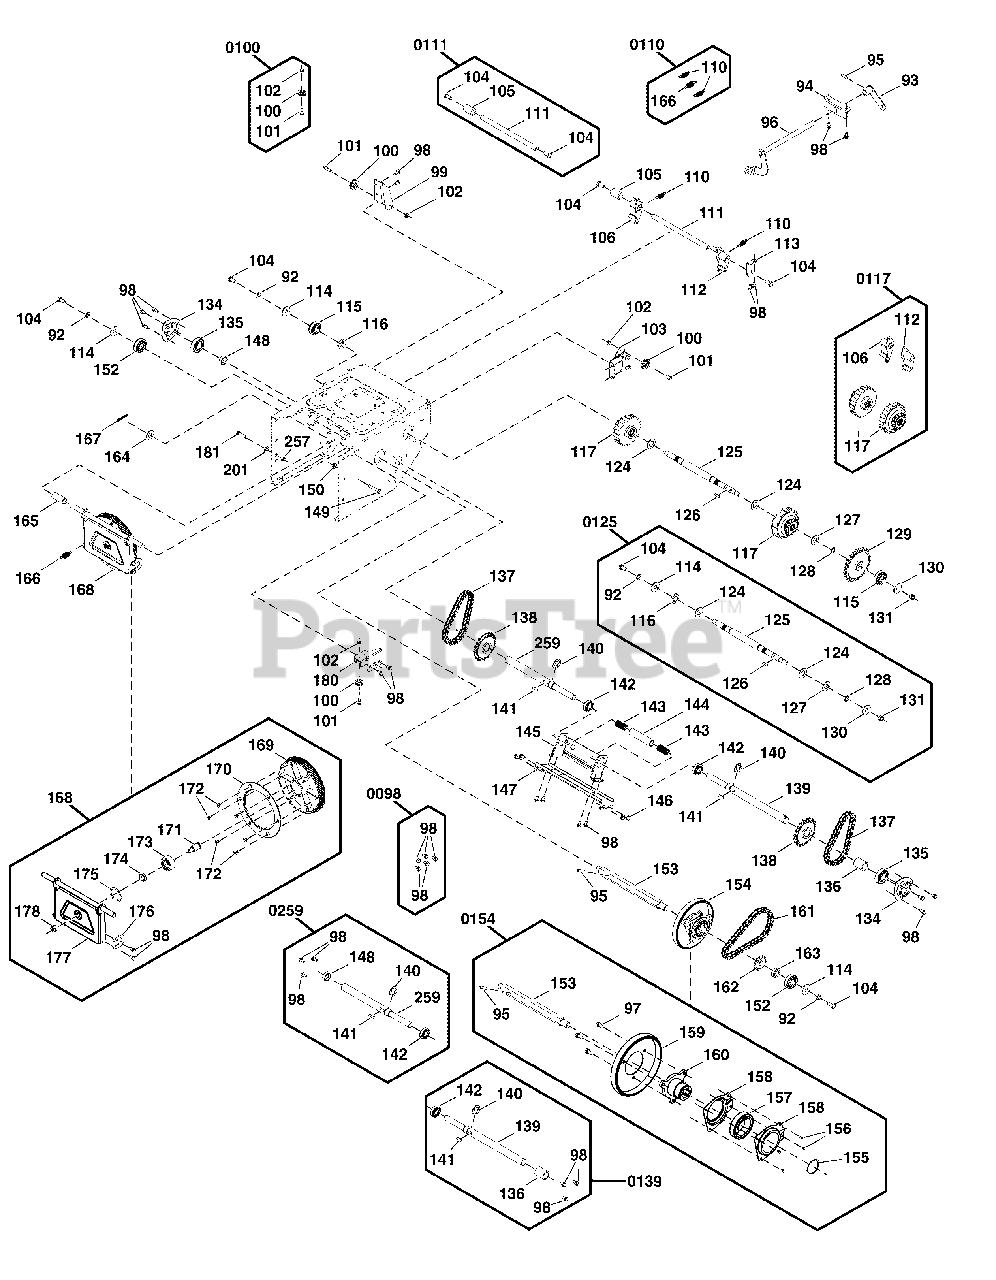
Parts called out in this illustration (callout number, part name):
93	ARM, Speed Select
94	BRACKET, Speed Select
95	PIN, Spring, 6 X 30
96	ROD, Speed Select, Fork
0098	KIT, Hardware
99	BRACKET, Cable Guide, Traction Control
0100	KIT, Pulley, Cable
100	PULLEY, Cable
101	SCREW, M6 X 12, Hex Head Shoulder
103	BRACKET, Cable Guide, Auger Control
105	SLEEVE, PAWL
106	PAWL Assembly, Right
0110	KIT, Spring, Traction Drive
110	SPRING, Pawl
0111	KIT, Shaft, Pawl
111	SHAFT, PAWL
112	PAWL Assembly, Left
115	BEARING, Ball
116	SPACER, SHAFT, DIFFERENTIAL
0117	KIT, Planitary and Pawl Assembly
117	GEAR, Planitary Assembly
0125	KIT, Shaft, Differential
125	SHAFT, DIFFERENTIAL
129	SPROCKET, 24T
134	RETAINER, Ball Bearing
135	BEARING, Ball
136	SLEEVE, Drive Shaft
137	CHAIN, Roller, 30
138	SPROCKET, 20T
143	SPRING, Drive Shaft
144	SLEEVE, Drive Shaft
145	BRACKET, Drive Shaft
147	PLATE, Drive Shaft Bracket
152	BEARING, Ball
154	FRICTION WHEEL ASSEMBLY
161	CHAIN, Roller, 36
162	SPROCKET, 10T
163	BUSHING, Hex Shaft
165	SLEEVE, Spacer, Swinging Plate
166	SPRING, Extension
168	ASSEMBLY, Friction Swinging Plate
169	PULLEY, Friction
170	COVER, Friction Pulley
173	BEARING, Ball
174	SLEEVE, Spacer, Swinging Plate
176	BRACKET, Swinging Plate
177	PLATE, Swinging
201	WASHER, 6x12x.7, Flat
